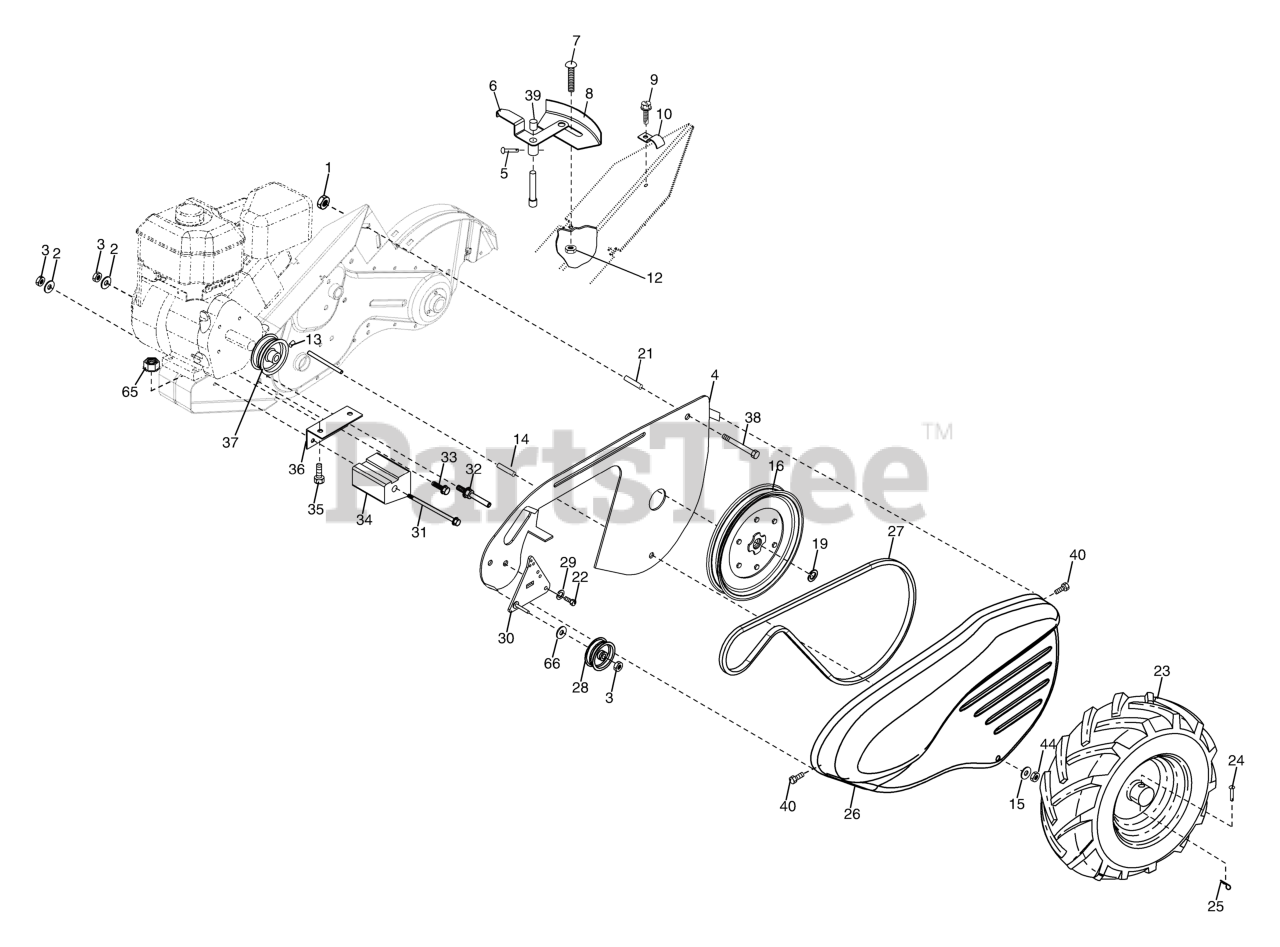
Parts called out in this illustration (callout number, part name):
1	NUT
2	WASHER, LOCK 3/8
3	NUT.HEX.3/8-16UNC
4	SHIELD
5	PIN.SPIROL.FLARED
6	LEVER ASM CRT
8	PANEL.INDICATOR.SHIFT.BLACK
9	TAPPING SCREW
10	CONDUIT.CLIP.PLATED
12	NUT
14	SPACER CRT
15	WASHER
16	SHEAVE, TRANSMISSION
19	RETAINING RING LT
21	SPACER-SPLIT.327 X .42
23	TIRE.16X4-8.CHEVRON.TILLER
23	RIM
23	VALVE STEM LT
24	RIVET,DRILLED
25	RETAINER M
26	RP BELT GUARD
27	V-BELT
28	PULLEY-IDLER TI
30	BRACKET.ASM.IDLER.BLACK
31	BOLT.FIN.HEX.3/8-16UNC
32	SHIFT ARM CRT
33	BOLT
34	COUNTERWEIGHT.LH.CRT
35	BOLT
36	BRACKET LH CRT
37	RP.ENGINE PULLEY
38	BOLT
39	CAP.PLUNGER.BLACK
40	SCREW.HEX.WSH.SLT.#10-24X.50
44	NUT.71038.31-18.HEX.NYLOCK
65	LOCKNUT-FLANGE 5/16-18
66	WASHER
